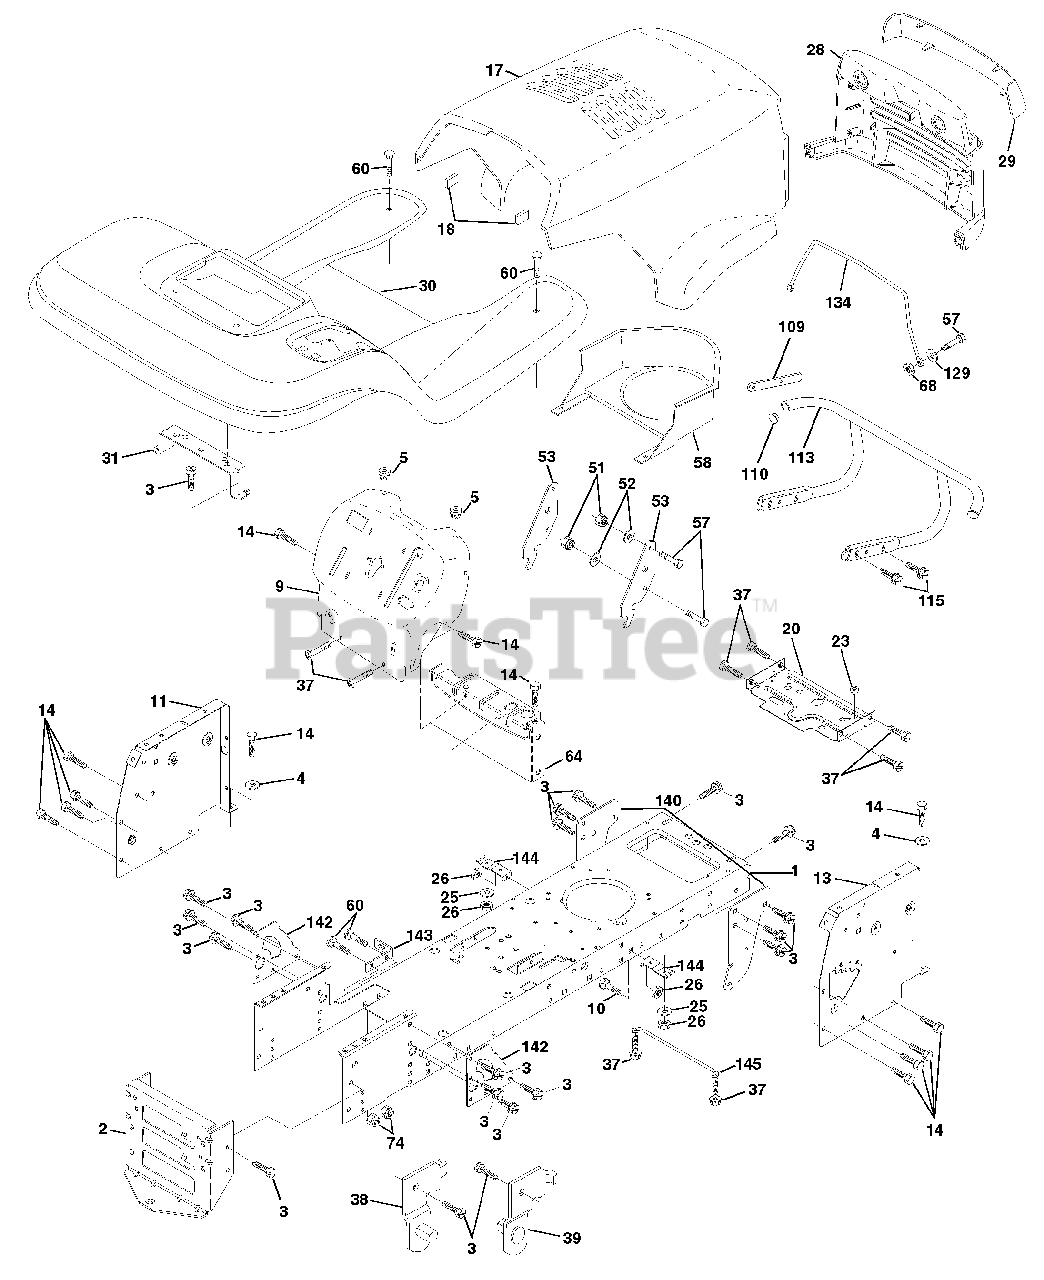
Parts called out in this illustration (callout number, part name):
1	Chassis STL Stamping 98
2	Drawbar, Stretch
3	Screw Thdrol 3/8-16x3/4 Ty-tt
4	Washer 13/32 x 3/4 x 16 Ga.
5	Bumper Hood/Dash
9	Dash P/L M, N/AMM N/HM Grey
10	Bolt Carriage 3/8-16 x 1
11	Panel Dash Lh
13	Panel Dash Rh
14	Screw Thdrol 3/8-16x1/2 Ty-tt
17	Hood LT/PL Husqvarna
18	Bumper Hood
20	Plate Mtg Battery Fuel Tank Fr
25	Washer 13/32 X 13/16 X 12 Ga
26	Nut Lock Hex W/Ins 3/8-16 Unc
28	Grille LT/PL Husqvarna
29	Lens LT/PL Husqvarna
30	Fender Footrest STLT Pnt
31	Bracket Support Fender
37	Screw Thdrol 6/16-18 x 1/2 TYT
38	Bracket, Asm. Pivot, L.H., Mower Rear
39	Bracket, Asm. Pivot, R.H., Mower Rear
51	Nut Lock Hex W/Ins 1/4-20
52	Washer 9/32 x 7/8 x 16 Ga.
53	Bracket Pnt. Pick off LT/PL Husqvarna
57	Bolt Hex 1/4-20 x 3/4
58	Air Duct Engine P/L
60	Bolt Rdhd Sqnk 3/8-16unc x 3/4
64	Dash Lower STLT
68	Nut Keps Hex 1/4-20 UNC
74	Nut Crownlock 3/8-16 UNC
109	Bracket Extension Bumper
110	Plug Plastic
113	Bumper Asm.
115	Screw Thdrol 3/8-16 x 1-1/4
129	Washer 9/32 x 5/8 x 16 Ga.
134	Rod Support Hood LT/PL Husq.
140	Bracket Suspension Front
142	Plate Reinforcement STLT
143	Bracket Swaybar Chassis
144	Bracket Pnt Footrest STLT
145	Rod Pivot Chassis/Hood
